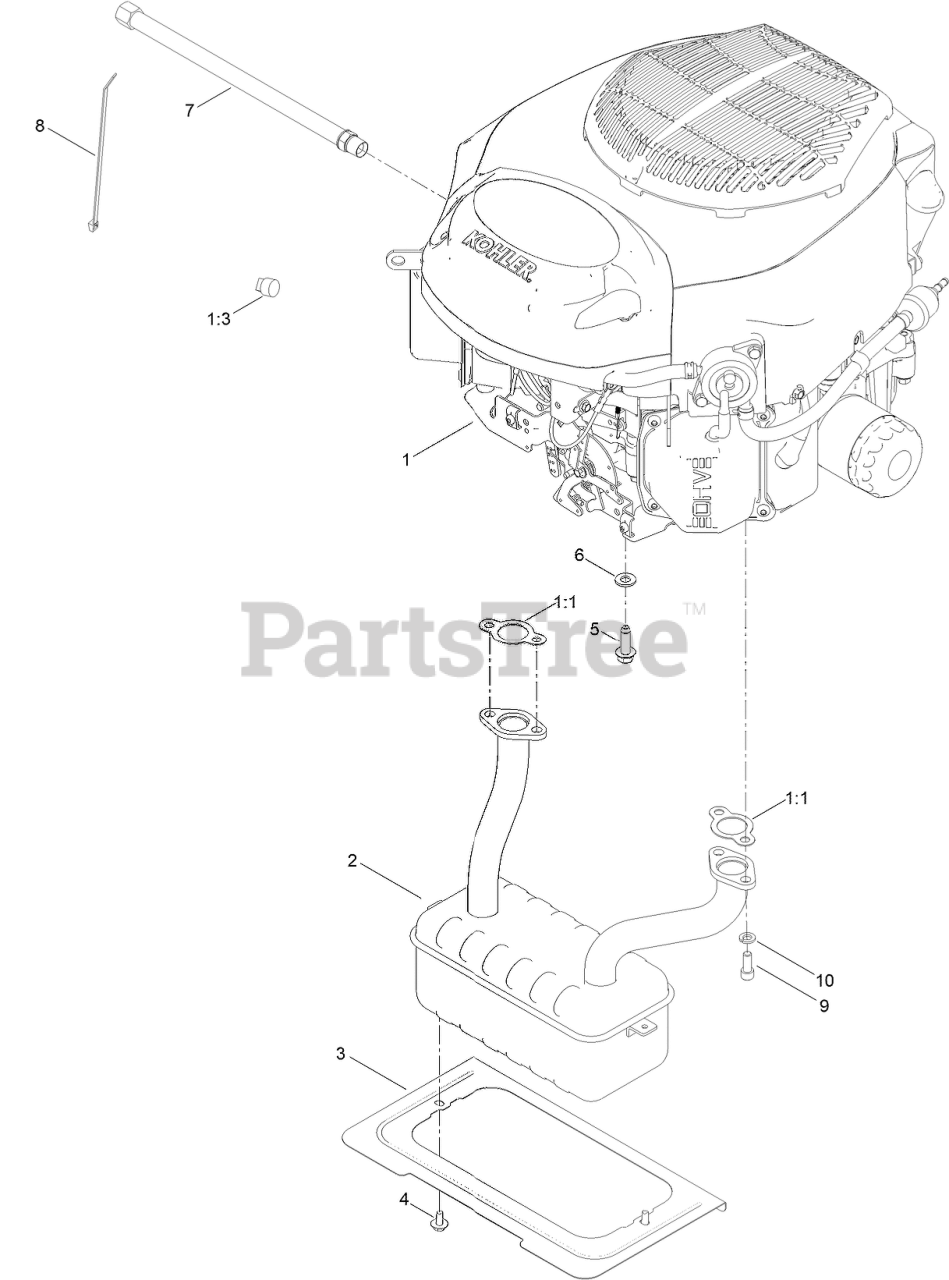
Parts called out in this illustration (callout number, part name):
1	ENGINE-KOHLER 24HP 7000 SERIES AUTOCHOKE
1:1	GASKET-EXHAUST
1:3	PLUG-PIPE, SQH
2	MUFFLER
3	SHIELD-HEAT
4	SCREW-HHFTF
5	SCREW-TAPTITE
6	WASHER-FLAT
7	HOSE-DRAIN, OIL
8	TIE-CABLE
9	SCREW-HSH
10	WASHER-LOCK
